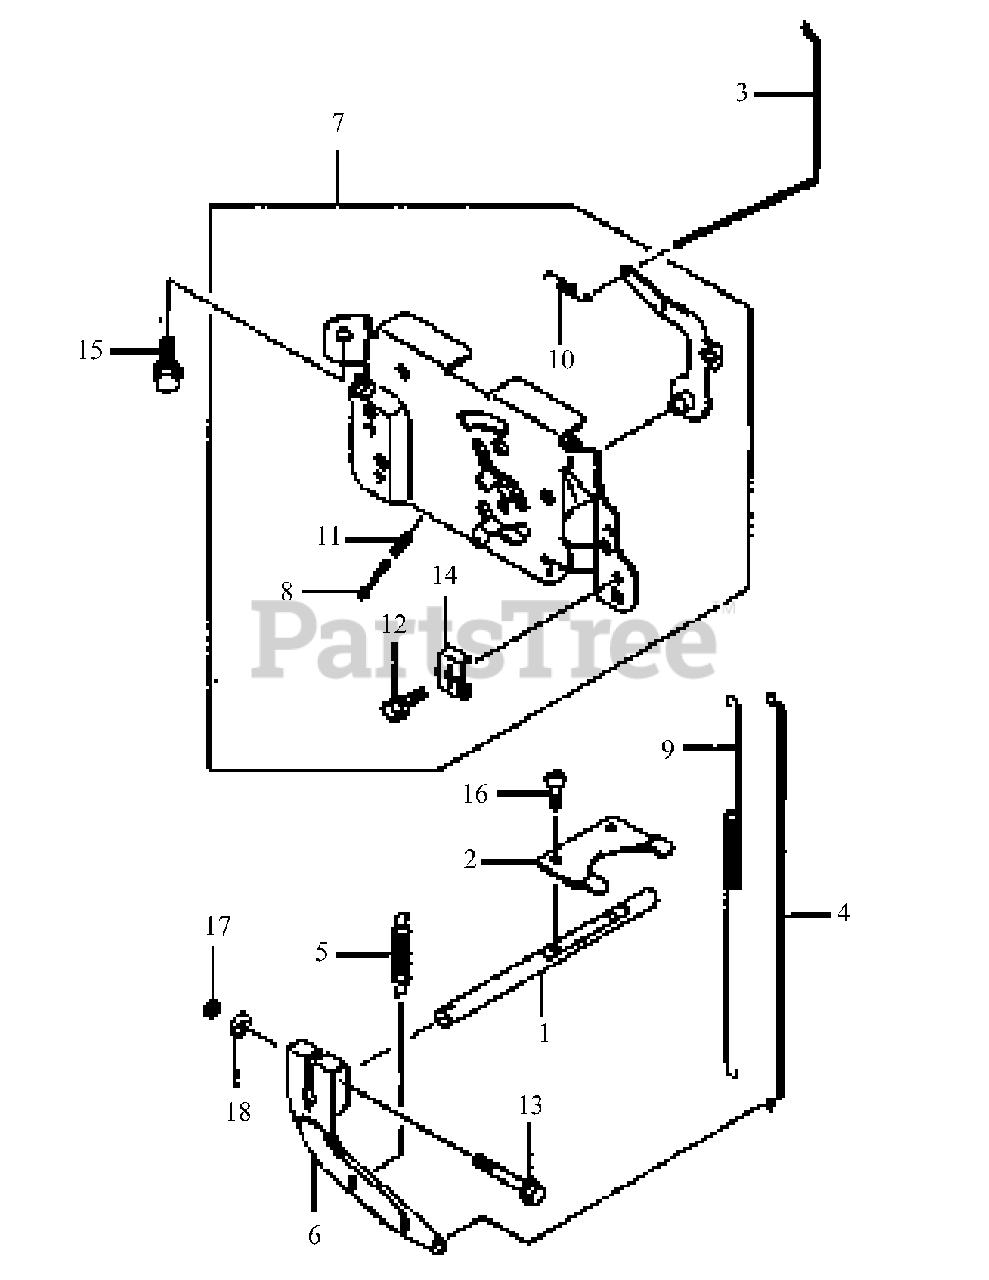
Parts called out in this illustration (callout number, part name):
1	Shaft
5	Spring, Governor
6	Arm, Governor
7	Panel, Control
10	Spring
15	Bolt, Flange
18	Washer, Plain
